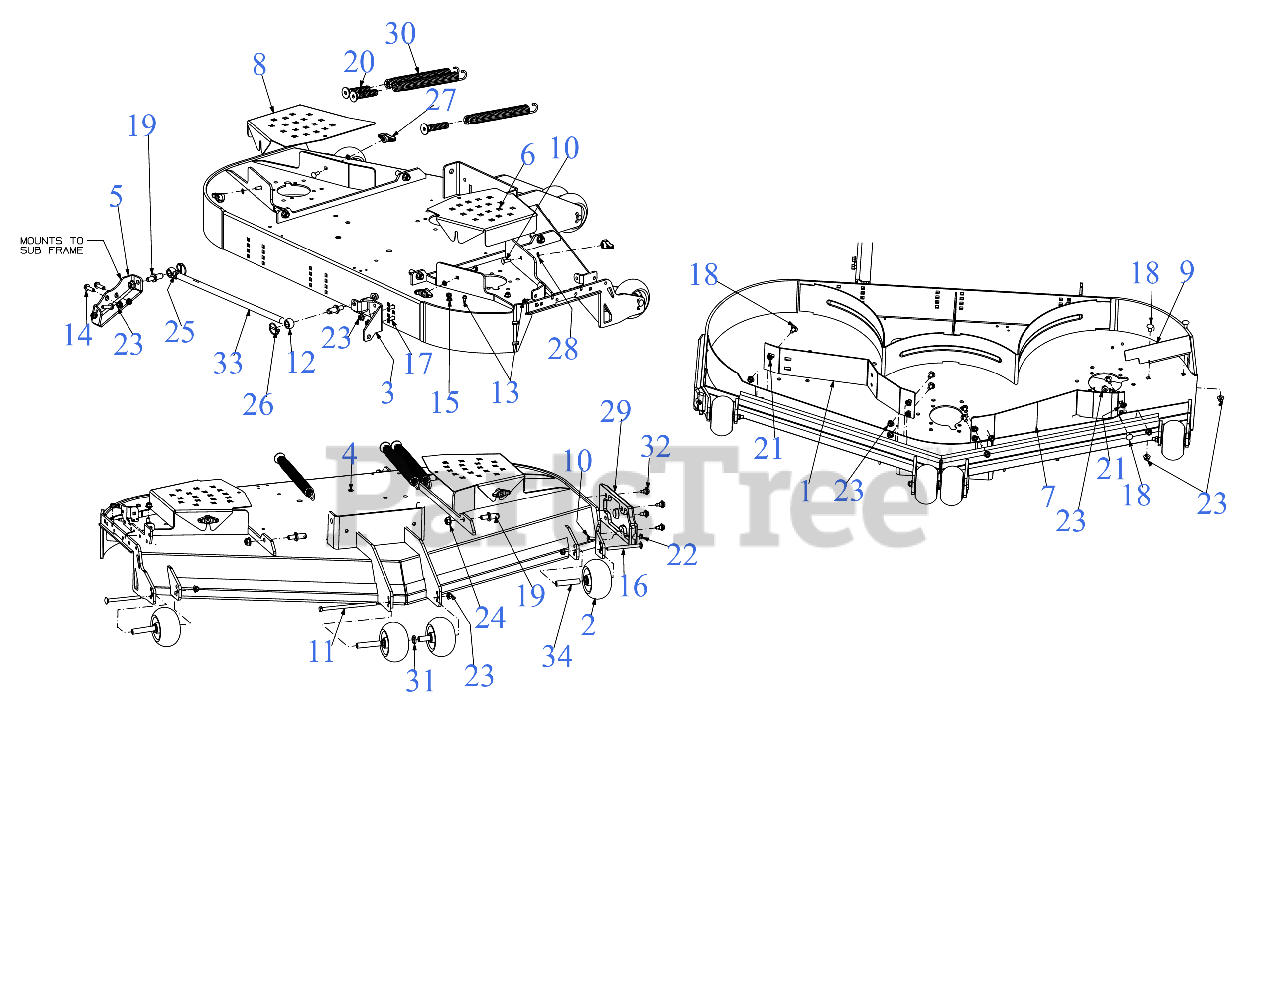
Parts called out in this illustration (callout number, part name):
1	BAFFLE - 60" ADJ
2	5" DIA DECK WHEEL COMPLETE
2	WHEEL BUSHING
5	STABILIZER MOUNTING BRACKET
10	CARRIAGE BOLT 5/16-18 x 1.00
11	SCREW 3/8-16 x 7.25 GR5
12	BOLT 5/8-16 x 2.63
13	SCREW 1/4-20 X.500
14	SCREW 3/8-16 x 1.25 GR5
15	SCREW 5/16-18 x .500
16	CARRIAGE BOLT 3/8-16 x 4.25 GR5
17	CARRIAGE BOLT 3/8-16 x 1.00 GR5
18	CARRIAGE BOLT 3/8-16 x .75
20	SPRING INSERT SCREW
22	FLANGE LOCK NUT 5/16-18
25	HEX JAM NUT
26	LYNCH PIN .1875
27	WING KNOB 5/16-18
29	DECK SKID PLATE (LH)
30	EXTENTION SPRING 1.20 x 11.35
31	FLAT WASHER .632X1.00X.16
32	SHOULDER SCREW .43X.29X5/16-18 TT
34	WHEEL SPACER .38ID x 3.04LG
